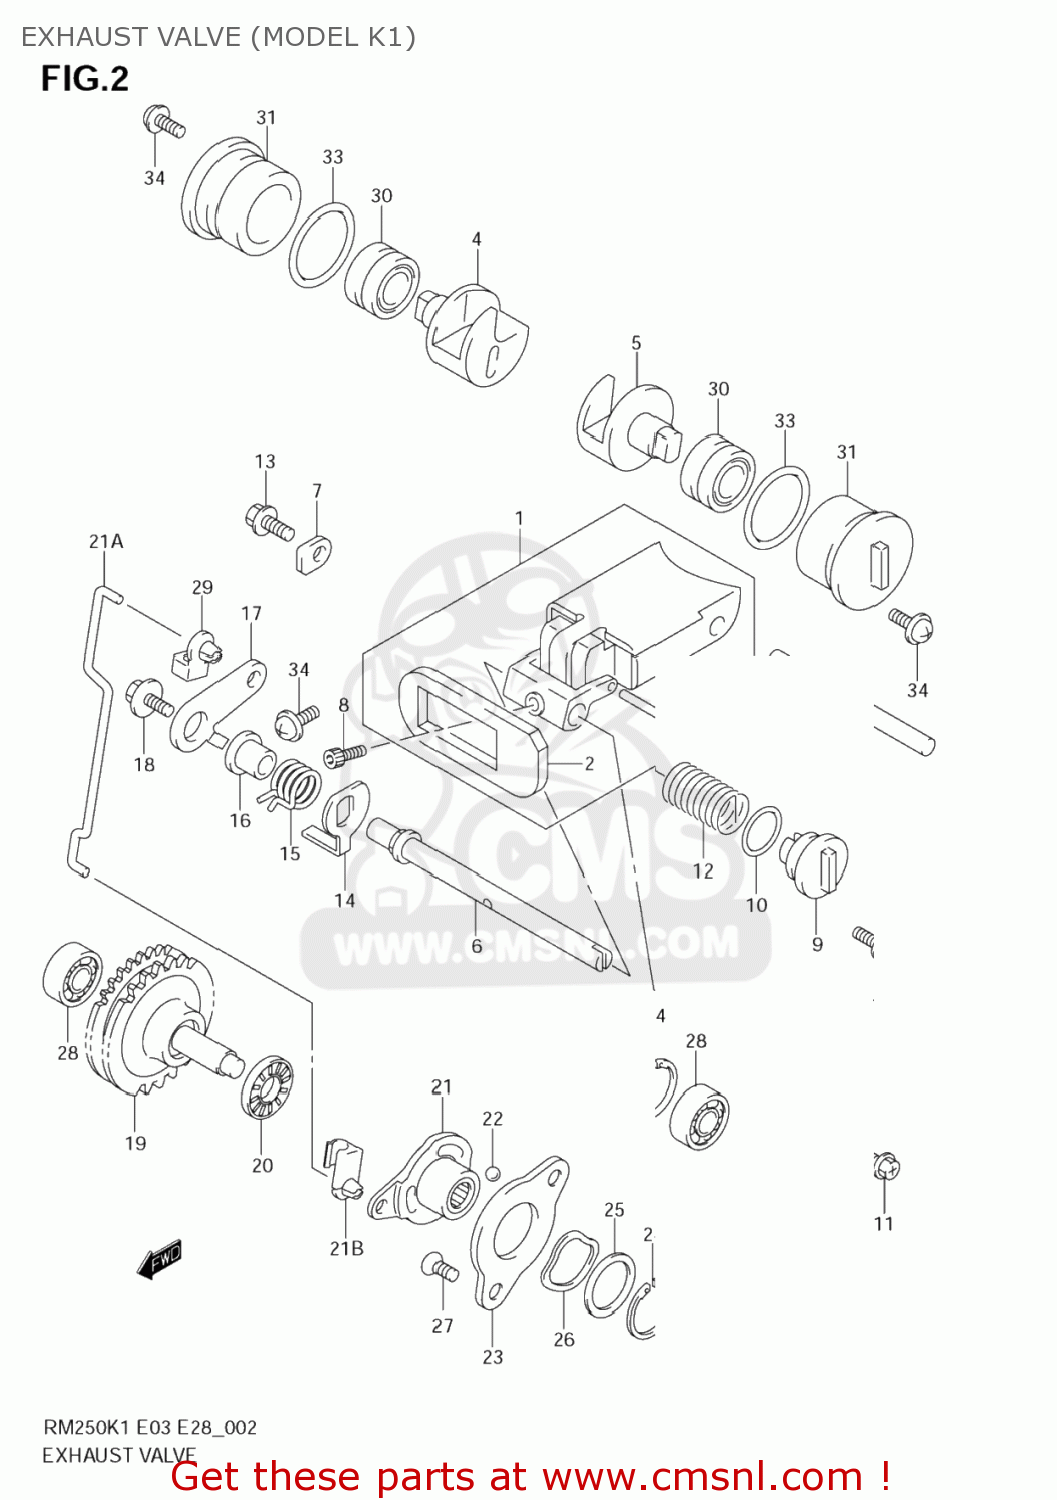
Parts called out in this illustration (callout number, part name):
1	VALVE ASSY,EXHAUST MAIN
2	GUIDE, EXHAUST VALVE
3	PIN(4X29.8)
4	VALVE, EXHAUST SIDE RH
5	VALVE,EXHAUST SIDE,L
6	SHAFT,EXHAUST VALVE
7	RETAINER
8	BOLT(4X8)
9	CAP,EXHAUST VALVE SHAFT SPRING
10	O RING(D:1.9,ID:14.5)
11	BOLT
12	SPRING,EXHAUST VALVE SHAFT
13	BOLT
14	LEVER,EXHAUST VALVE NO.2
15	SPRING
16	SPACER,EXHAUST VALVE
17	LEVER,EXHAUST VALVE NO.1
18	BOLT(5X12)
19	GOVERNOR ASSY,EXHAUST VALVE
20	BEARING(10X22X2.8)
21	ACTUATOR,EXHAUST VALVE
21A	ROD,EXHAUST VALVE
21B	BUSH,EXHAUST VALVE ROD NO.1
22	BALL
23	STARTER,EXHAUST VALVE ACTUATOR
24	CIRCLIP
25	SHIM(19.1X25X0.3)
26	WASHER
27	SCREW(5X10)
28	BEARING(8X22X7)
29	BUSH,EXHAUST VALVE ROD NO.1
30	BEARING(12X24X13)
31	CAP,EXHAUST SIDE VALVE
32	PIN
33	O RING(D:1.9,ID:28.3)
34	SCREW 5X12
